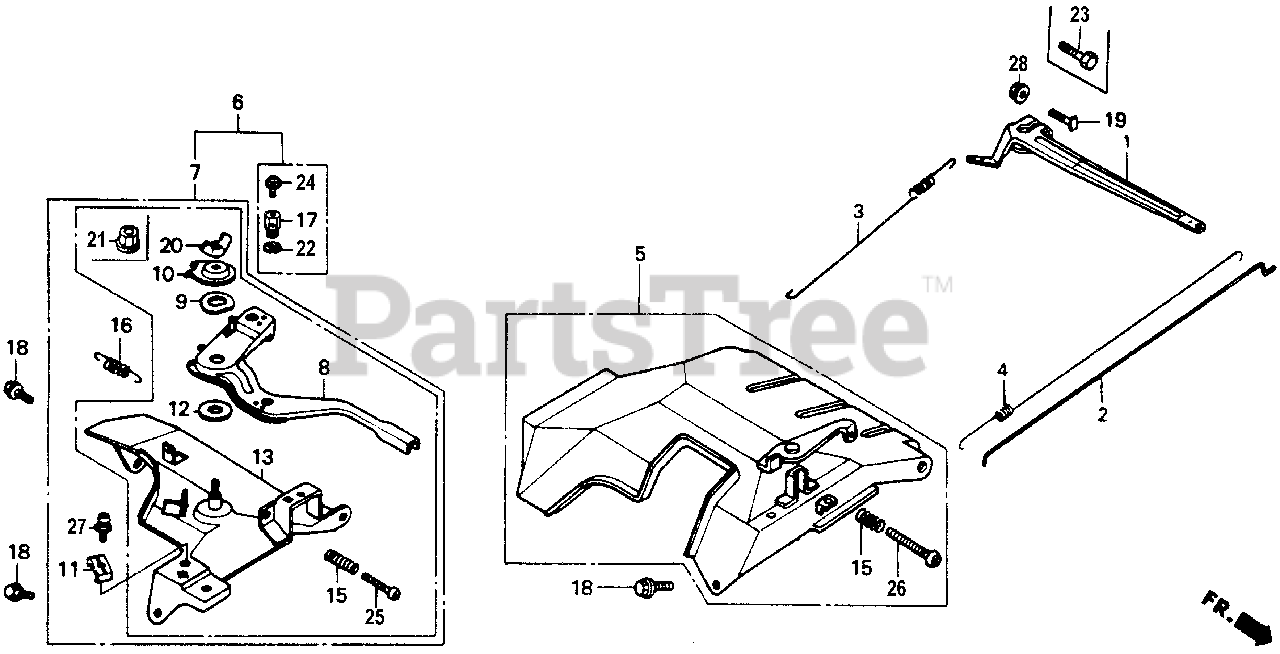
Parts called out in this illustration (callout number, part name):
1	ARM, GOVERNOR
2	ROD, GOVERNOR
3	SPRING, GOVERNOR
4	SPRING, THROTTLE RETURN
7	CONTROL ASSY. (REMOTE)
8	LEVER, CONTROL
9	SPRING, LEVER
10	WASHER, CONTROL LEVER
11	HOLDER, CABLE
12	SPACER, CONTROL LEVER
13	BASE, CONTROL
15	SPRING, CONTROL ADJUSTING
16	SPRING, CABLE RETURN
18	BOLT, FLANGE (6X12) (CT200)
19	BOLT, GOVERNOR ARM
20	WINGNUT (6MM)
21	NUT, SELF-LOCK (6MM)
23	BOLT, HEX. (6X22)
25	SCREW, PAN (5X32)
27	SCREW, PAN (5X16)
27	SCREW-WASHER (5X16)
28	NUT, FLANGE (6MM)
